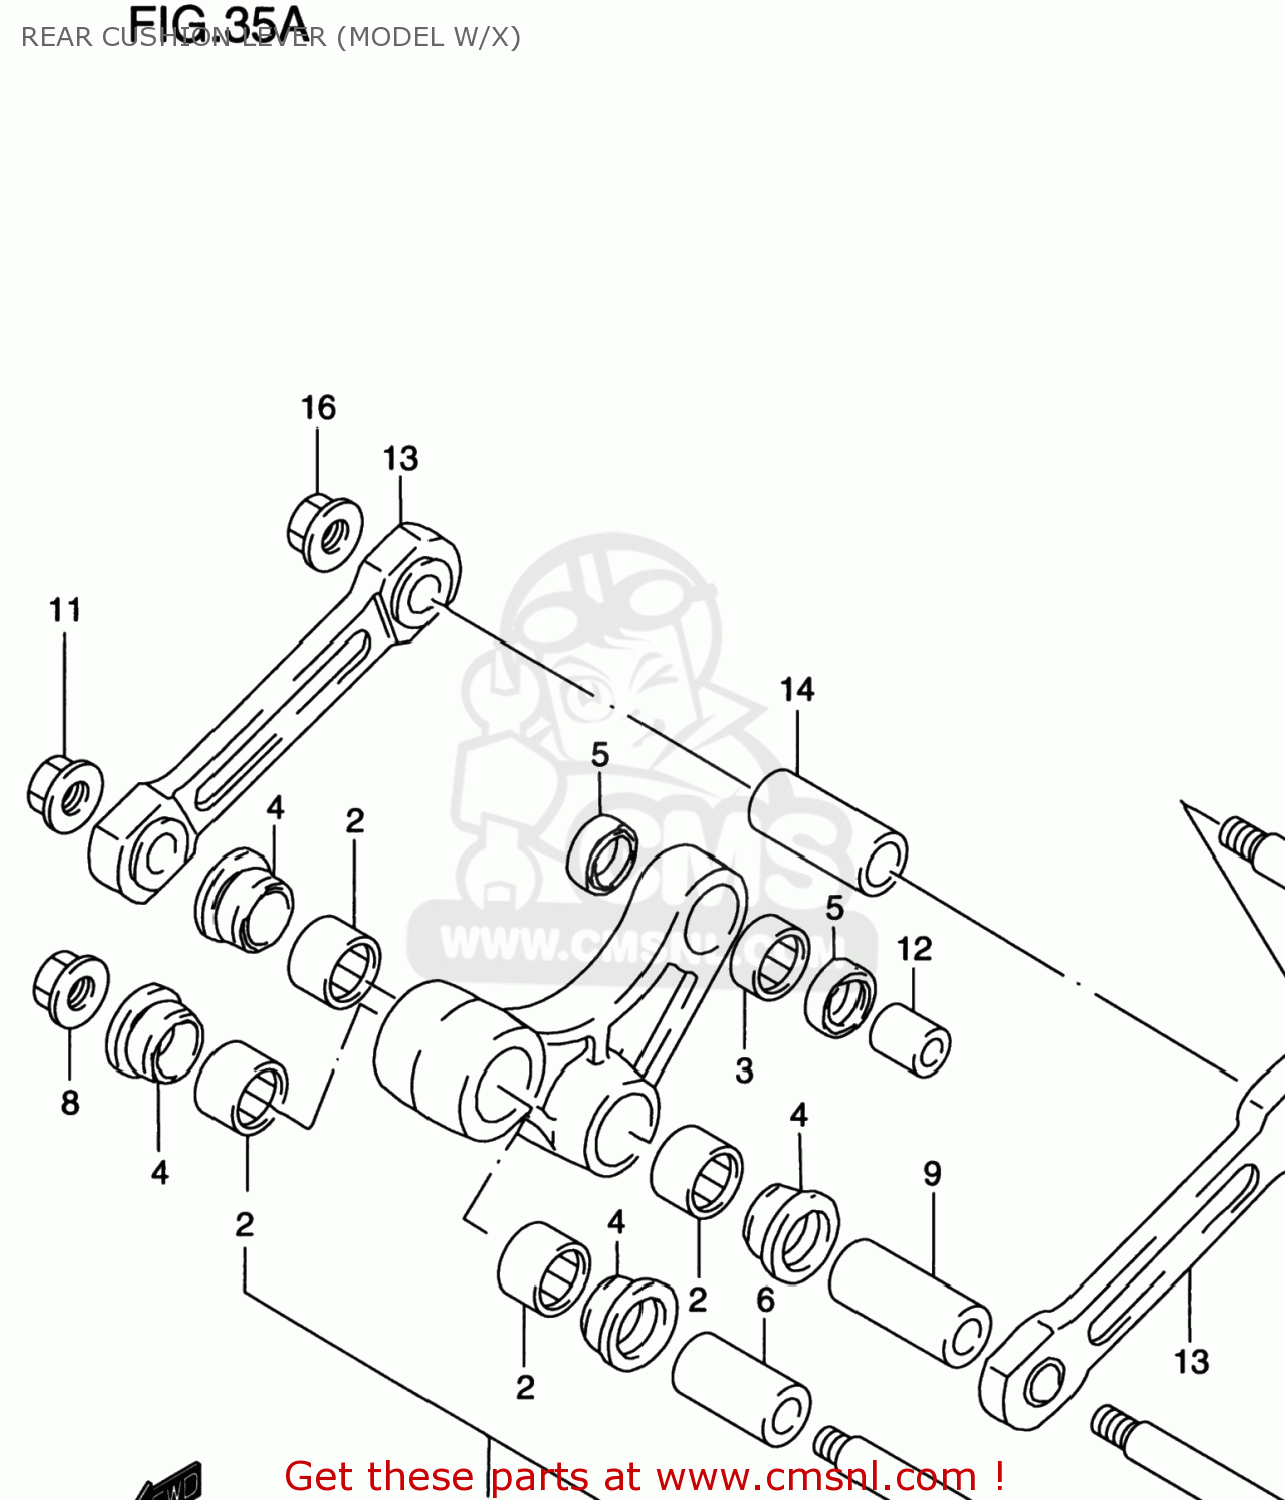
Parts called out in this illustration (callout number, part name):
1	LEVER SET,RR CUSHION
2	BEARING(22X28X16)
3	BEARING(20X26X12)
4	SEAL,SWINGING ARM RR
5	SEAL,OIL(20X26X4.5)
6	SPACER,RR CUSHION LEVER FR
7	BOLT,REAR CUSHION LEVER
8	NUT 12MM
9	SPACER,RR CUSHION
10	BOLT,REAR CUSHION
11	NUT 12MM
12	SPACER,RR CUSHION LEVER RR
13	ROD SET,REAR CUSHION
14	SPACER,RR CUSHION
15	BOLT,REAR CUSHION
16	NUT 12MM
